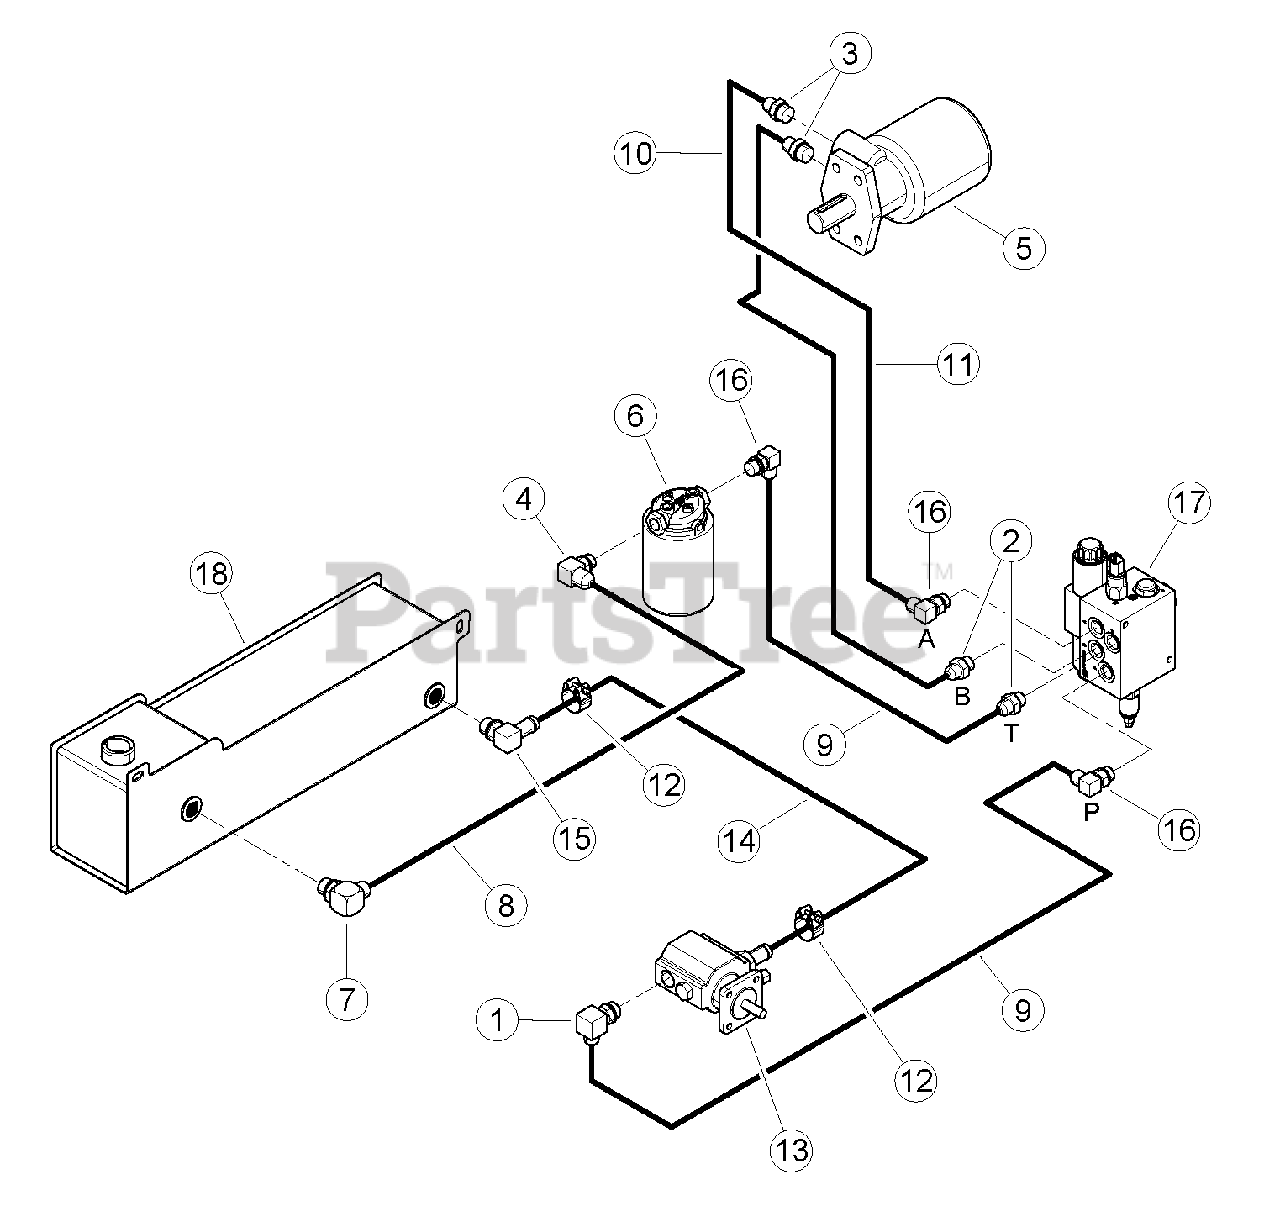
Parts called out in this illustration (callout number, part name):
1	ADAPTER, -10 MORING / -8 MJIC 90 DEG.
2	ADAPTER, -8 MORING / -8 MJIC
3	ADAPTER, -10 MORING / -8 MJIC
4	ADAPTER, -8 MORING / -10 MJIC 90 DEG.
5	MOTOR, 45 CU IN HYDRAULIC
6	ASSEMBLY, HYDRAUILC FILTER
7	ADAPTER, -10 MORING / -10 MJIC 90 DEG.
8	HOSE ASSEMBLY, -10 FMJ / -10 FMJ LD 90 DEG. X 21"
9	HOSE ASSEMBLY, -8 FMJIC / -8 FMJIC 90 DEG. X 21"
10	HOSE ASSEMBLY, -8 FMJIC / -8 FMJIC 90 DEG. X 61"
11	HOSE ASSEMBLY, -8 FMJIC / -8 FMJIC X 61"
12	CLAMP, 1-5/32 TO 7/32 OD RANGE T-BOLT
13	PUMP, 2 STAGE CW HI/LO 0.605 DISP.
14	HOSE, .75 ID X 24 IN. 100R4 HYD
15	ADAPTER, -10 MORING / .75 90 DEG. HOSE
16	ADAPTER, -8 MORING / -8 MJIC 90 DEG.
17	ASSEMBLY, HYDRAULIC FEED FLOW VALVE
18	WELDMENT, HYDRAULIC TANK
